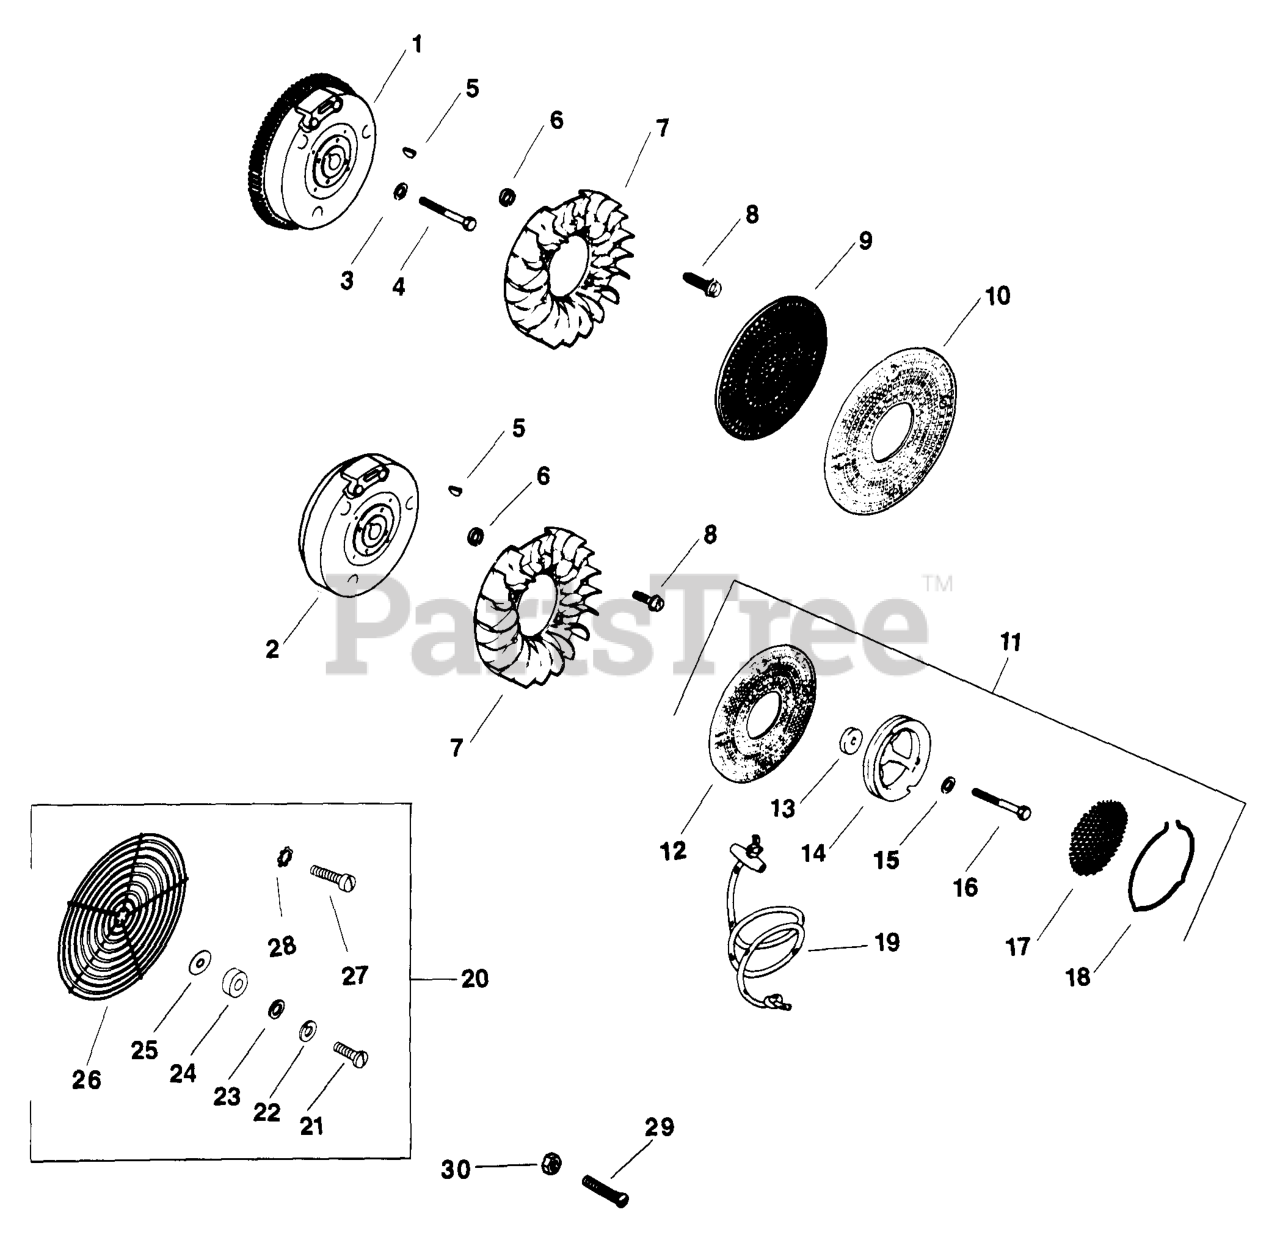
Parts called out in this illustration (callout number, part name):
1	FLYWHEEL - DISCONTINUED
3	WASHER (KM)-USE 12 468 03-S
4	SCREW, MACH 3/8-24X1-1/4"
5	KEY, 3/16" X 1"
8	SCREW, WSH HD 1/4-20X5/8" - DISCONTINUED
9	SCREEN, GRASS
